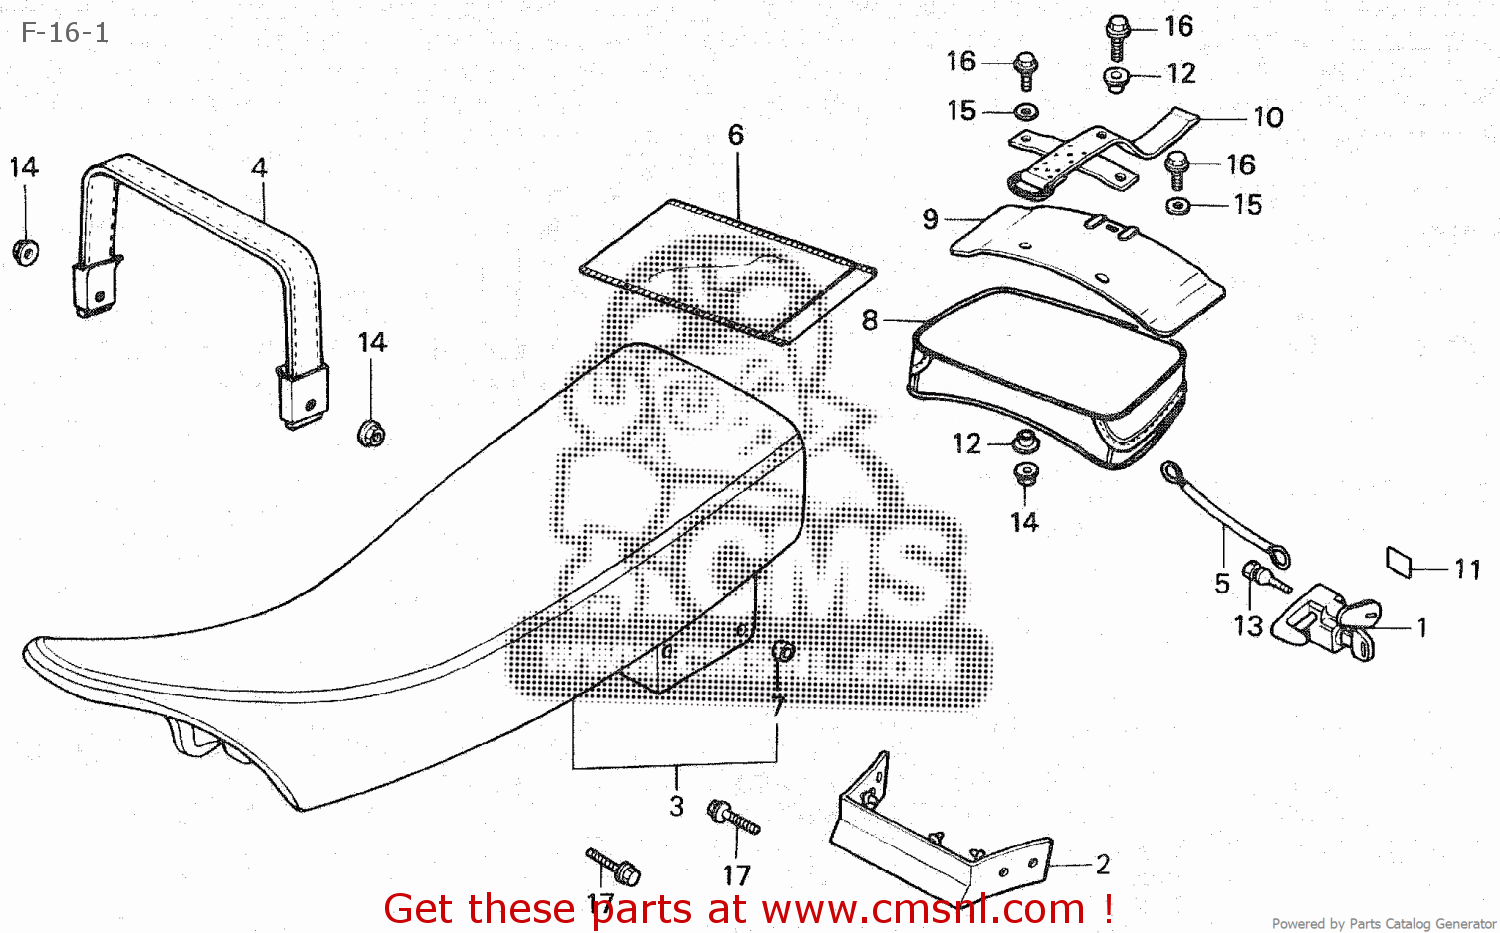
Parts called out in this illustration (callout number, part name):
1	HOLDER,HELMET
2	RUBBER,SEAT UNDER
3	SEAT COMP.
4	BELT COMP.,SEAT
5	WIRE,TAIL BAG LOC
6	BAG,SERVICE BOOK
7	COLLAR,RR.FENDER
8	BAG COMP.,TAIL
9	PLATE,TAIL BAG BO
10	BAND COMP.,TAIL B
11	LABEL,HELMET HOLD 30X15MM
12	COLLAR C
13	BOLT B,SPL,6MM
15	WASHER,PLAIN,6MM
16	BOLT.FLANGE 6X20
17	BOLT,FLG DR 8X18
